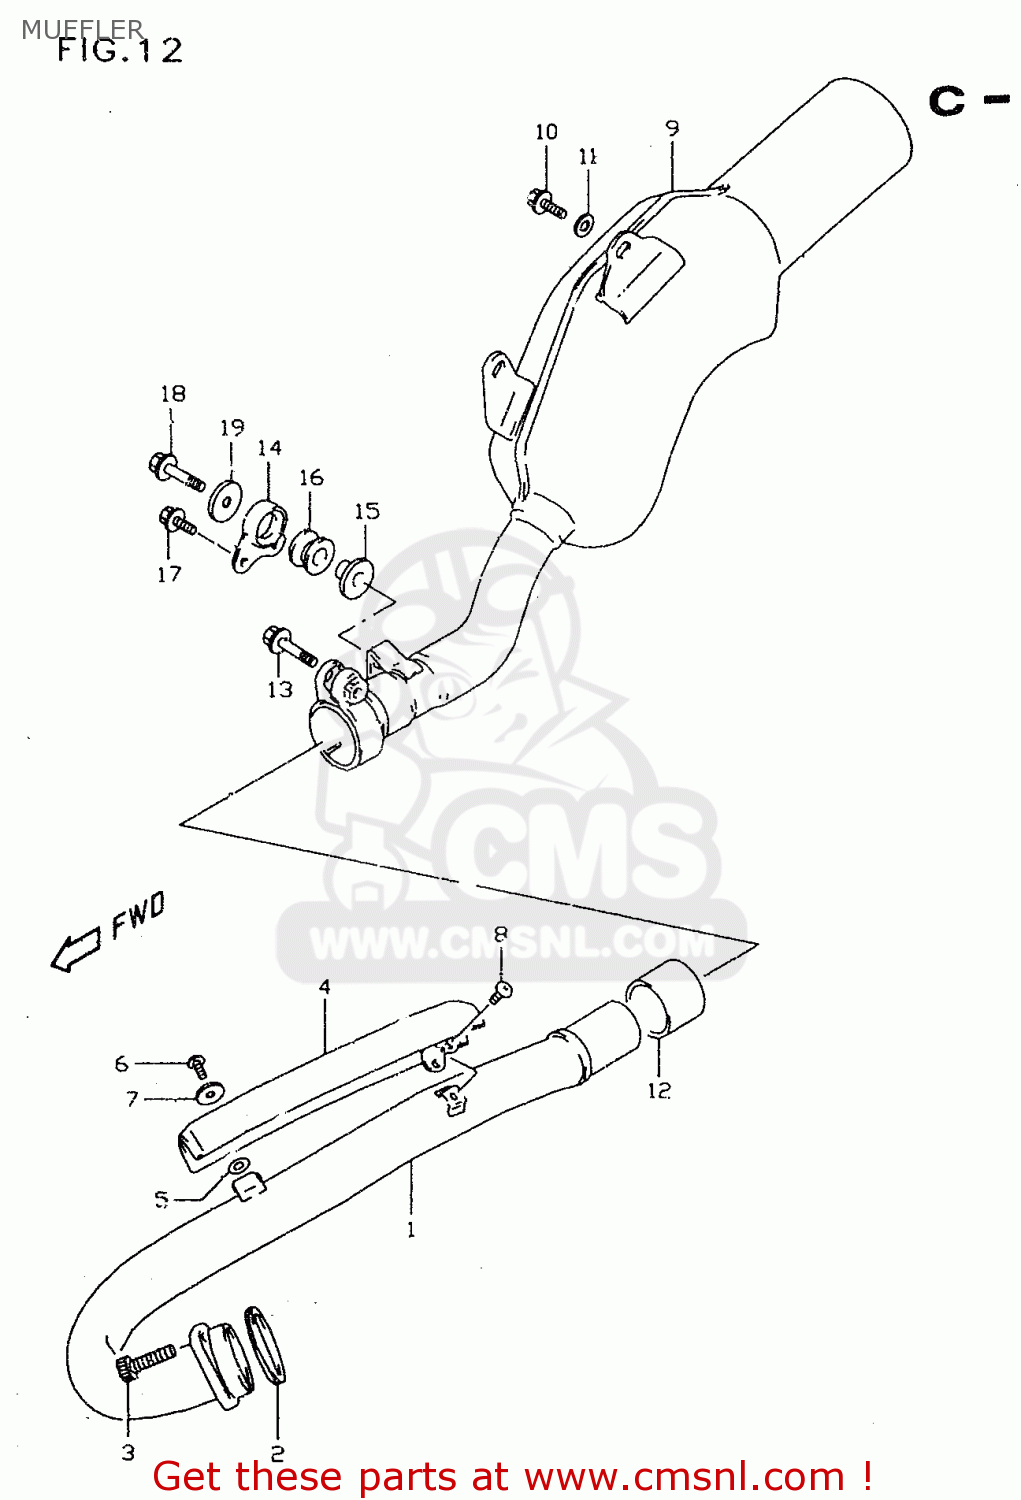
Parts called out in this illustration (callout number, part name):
1	PIPE,EXHAUST
2	GASKET,EXHAUST PIPE (NAS)
3	BOLT
4	COVER,EXHAUST PIPE
5	GASKET(5.8X13X1.4) (NAS)
6	SCREW(6X10)
7	WASHER(6.5X18X1)
8	SCREW
9	BODY,MUFFLER
10	BOLT(8X20)
11	WASHER (8.5X19X2.3)
12	CONNECTOR,MUFFLER
13	BOLT
14	DAMPER,MUFFLER SUPPORT JOINT
15	SPACER(8.6X12X17.5)
16	CUSHION
17	BOLT
18	BOLT(8X35)
19	WASHER(8.5X28X1.6)
